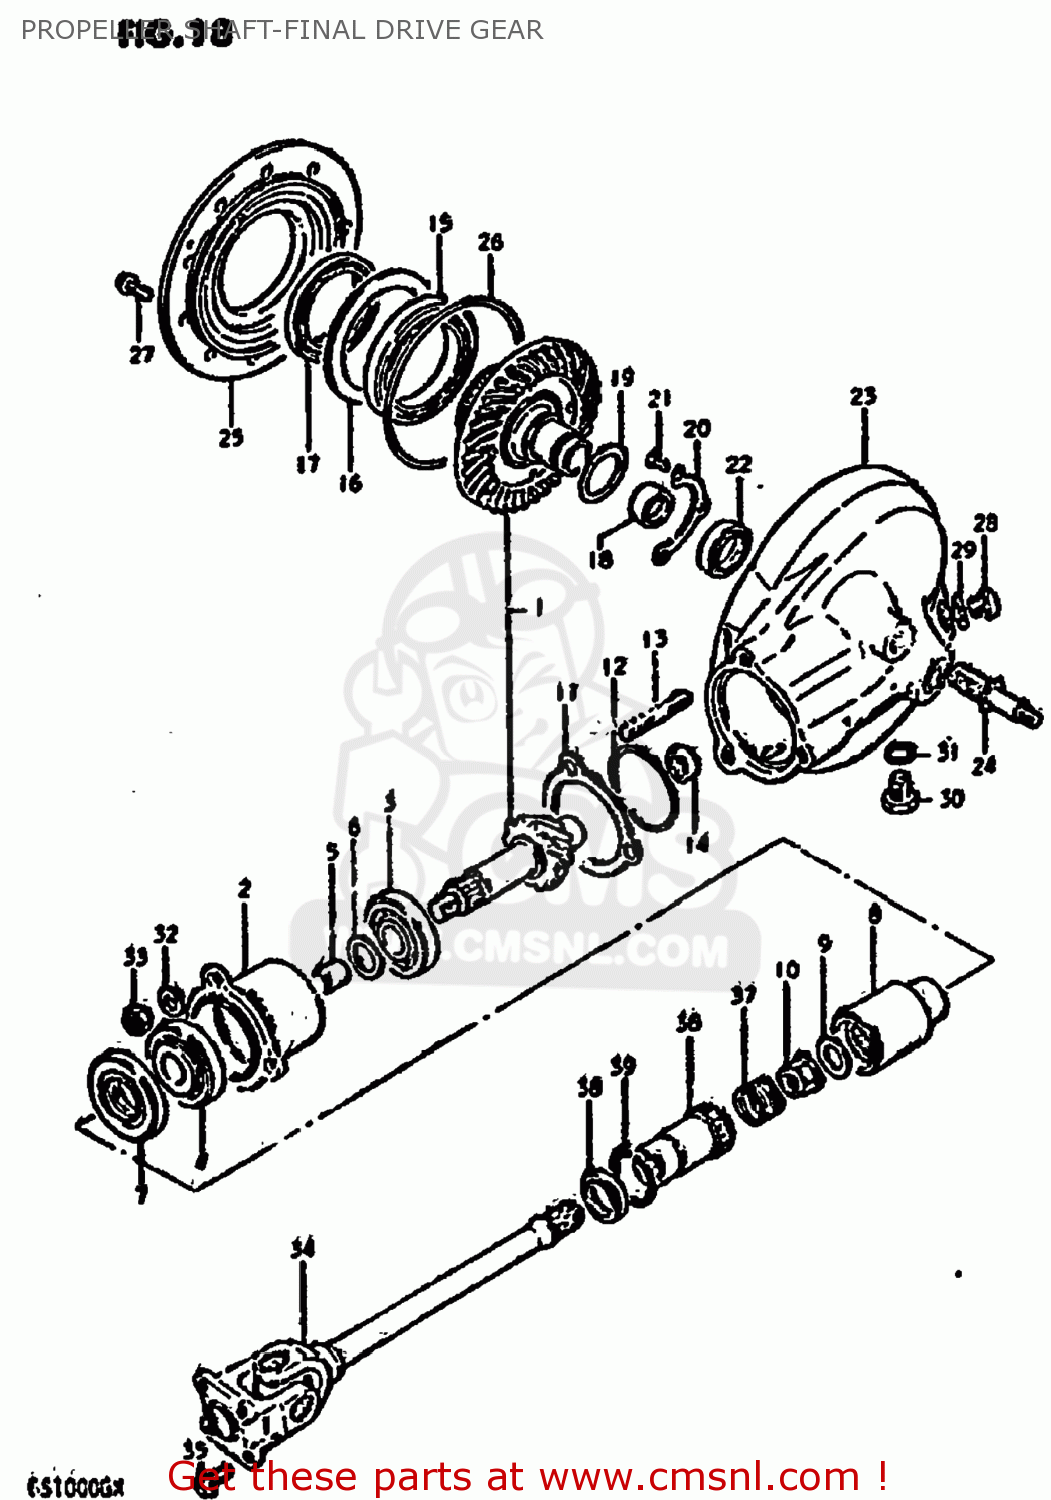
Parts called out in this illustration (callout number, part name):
1	GEAR SET,FINAL BEVEL
2	HOUSING,DRIVE GEAR
3	BEARING(25X52X19.25)
4	BEARING
5	SPACER (25.2X30X3.5)
6	SHIM (25X30X2
7	SEAL,OIL(32X54X7)
8	GEAR,FINAL DRIVE
9	WASHER(14X29X4)
10	NUT
11	SHIM,DRIVE GEAR HOUSING
12	O RING(D:2.4,ID:62.6)
13	STUD 10X30
14	BEARING(24X33X17)
15	BEARING(70X110X13)
16	SHIM,DRIVEN GEAR BEARING
17	SEAL,OIL(70X96X16)
18	BEARING(35X48X23.7)
19	SHIM,FINAL DRIVEN GEAR
20	RETAINER,FINAL DRIVEN GEAR BRG
21	SCREW 6X12
22	SEAL,OIL(30X42X7)
23	CASE ASSEMBLY,FINAL GEAR
24	STUD
25	CASE,FINAL GEAR BEARING
26	O-RING (D:3.1 ID:144.4)
27	BOLT
28	PLUG (14X12)
29	GASKET(14X19.2X2) (NAS)
30	PLUG
31	GASKET(14X19.2X2) (NAS)
32	LOCK WASHER
33	NUT
34	SHAFT ASSEMBLY,PROPELLER
35	BOLT(8X17)
36	COUPLING,PROPELLER SHAFT
37	SPRING
38	SEAL,OIL(30X40.5X5.5)
39	CIRCLIP
